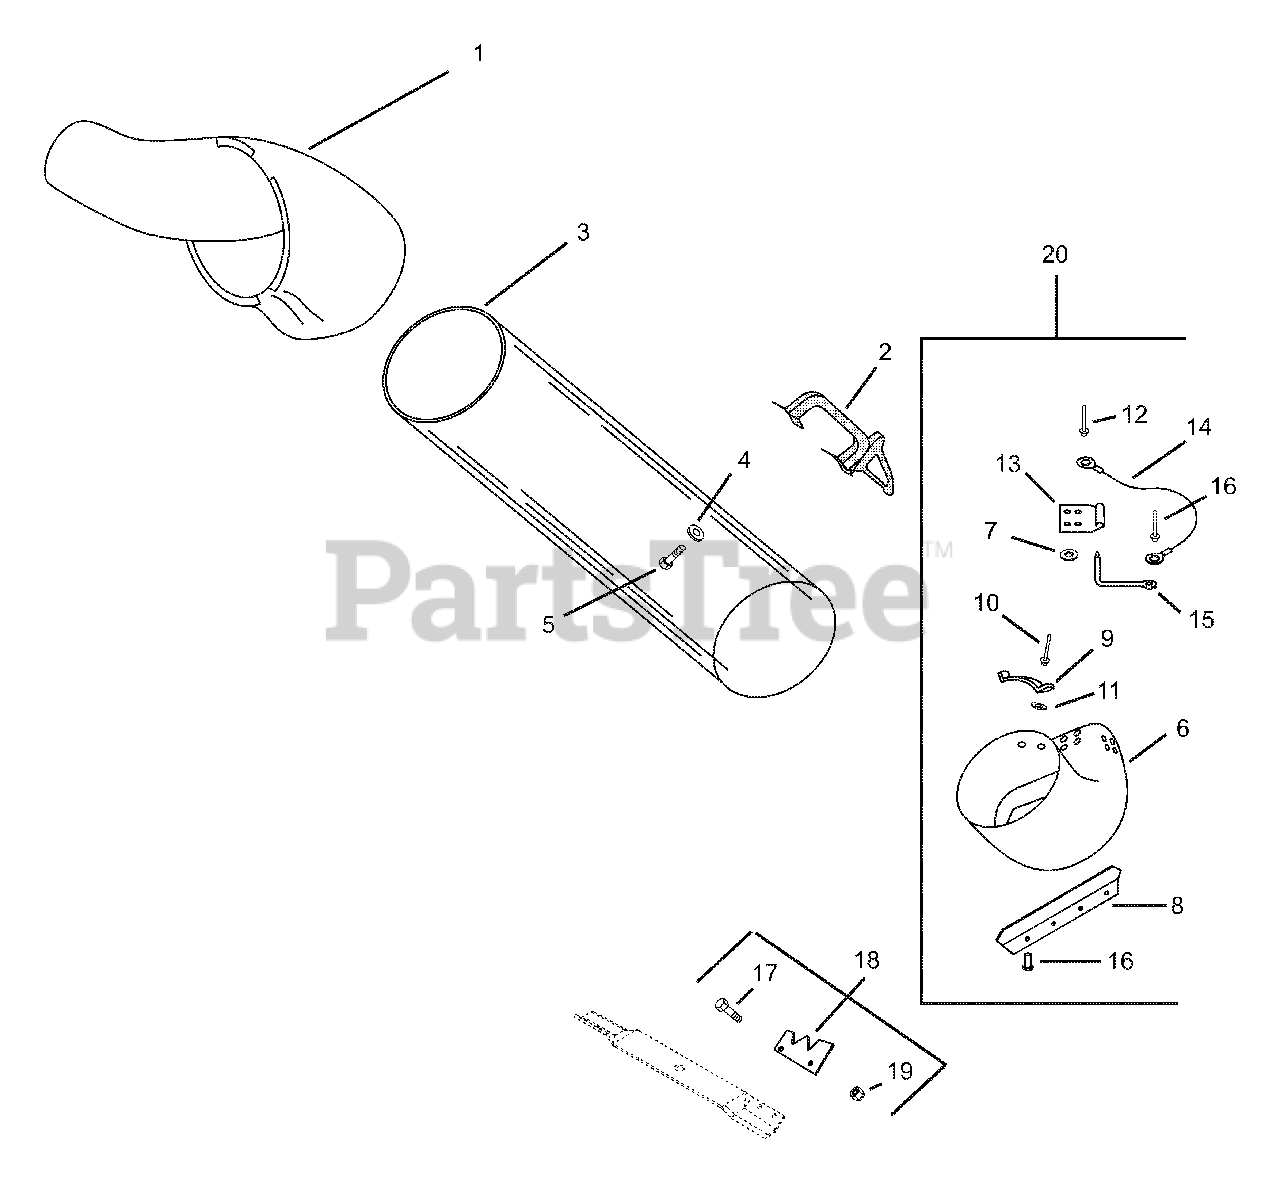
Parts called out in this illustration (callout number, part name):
1	Upper Boot
2	Tub Handle
3	Bagger Tube
4	Washer-Flat-Steel .268 x .562 x .046
5	Screw-Tapping 10-16 x .75
6	Pan Head Boot Assembly
7	Washer-Flat-Steel .194 x .492 x .047
8	Extension-Chute
9	Tube Retainer Clip
10	Rivet-Pop .187 x .527
11	Washer-Flat-Steel .215 x .56 x .085
12	Rivet-Pop .187 x .402
13	Boot Bracket
14	Lanyard
15	Pull Pin
16	Rivet-Tubular .187 x .375
17	Bolt-Hex .31-24 x .75 Grade 8
18	Vane Service Assembly
19	Nut-Locking Top .312-24
20	Mower Boot Assembly - 40"
